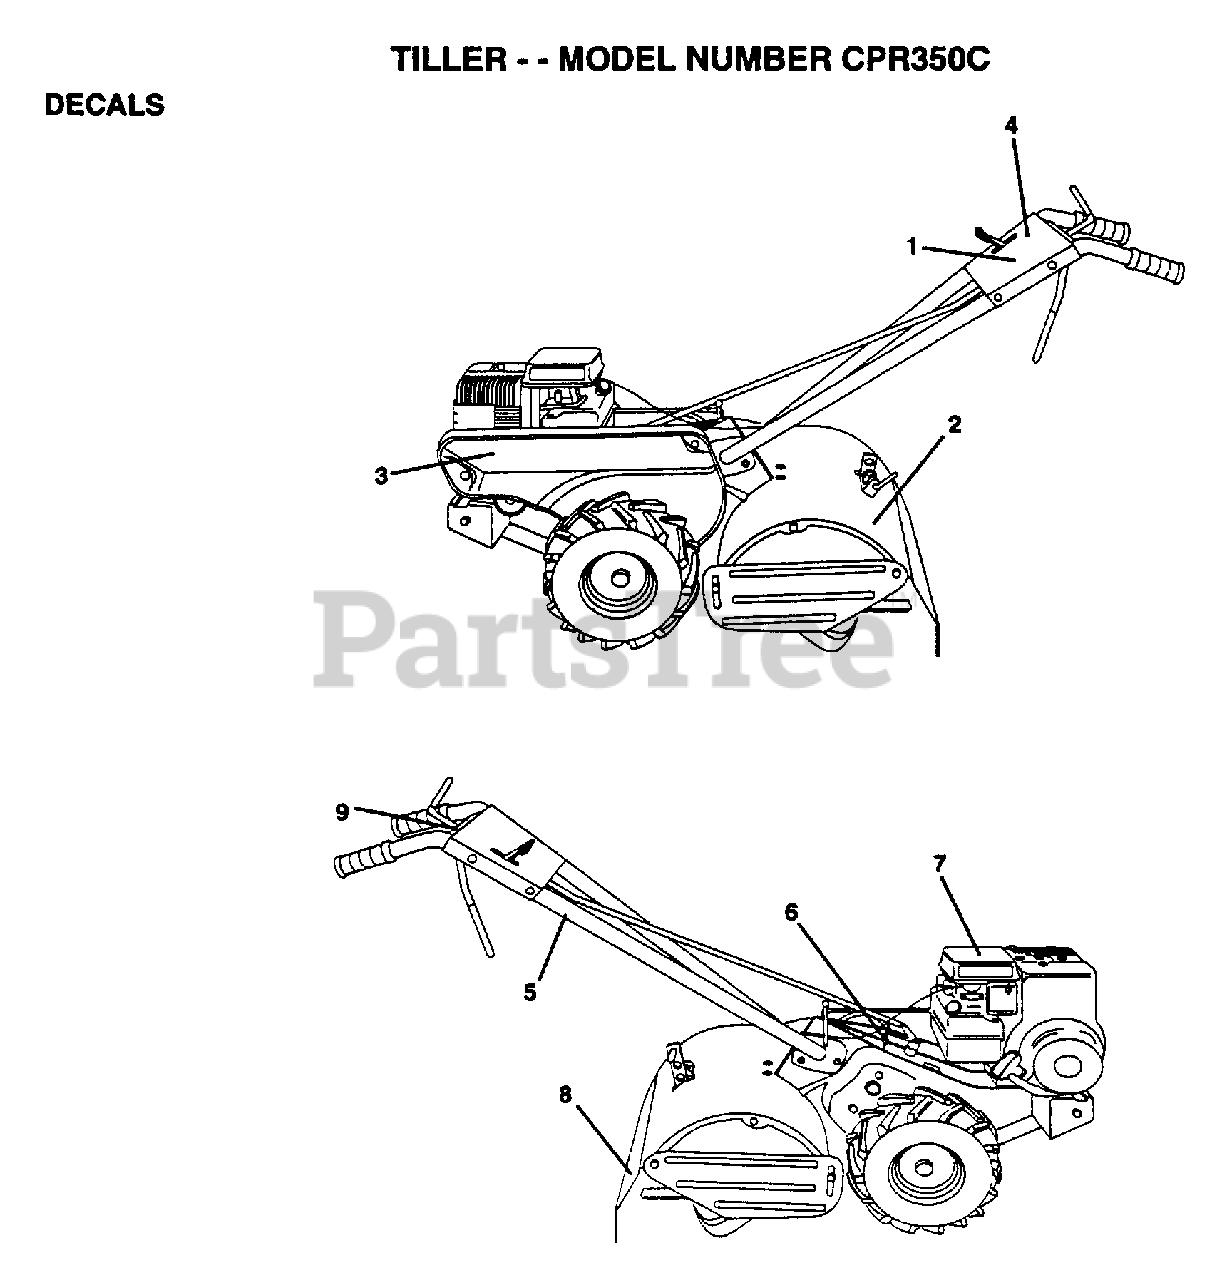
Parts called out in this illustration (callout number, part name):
1	DECAL.PNL.CNTL.
2	DECAL, LOGO
3	DECAL.GUARD.BELT
4	DECAL, PANEL CONTROL
5	DECAL TI
6	DECAL CRT
8	DECAL TI
